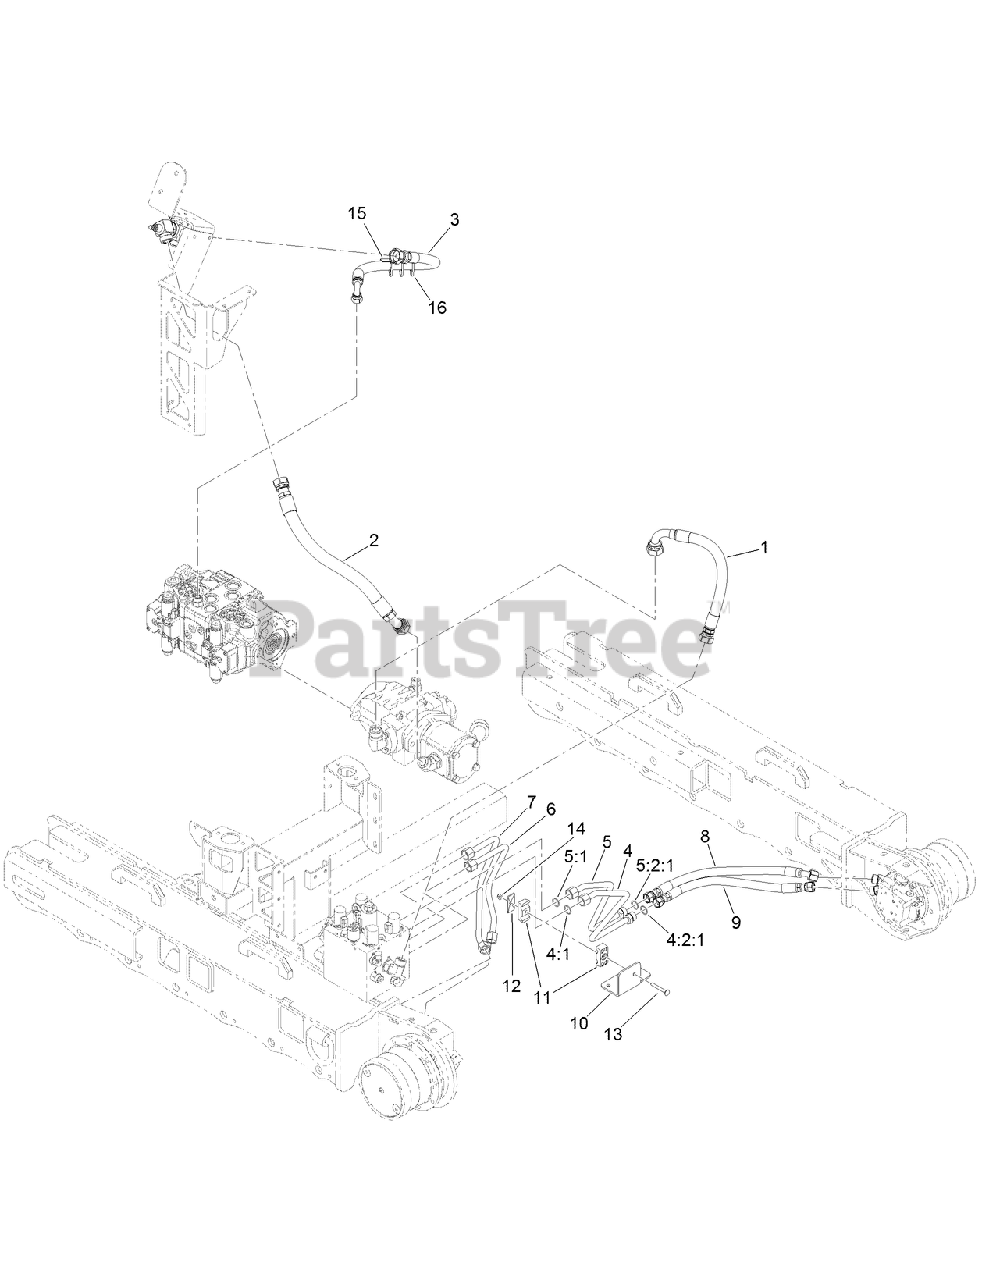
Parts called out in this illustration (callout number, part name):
1	HOSE ASM-HYD
2	HOSE ASM-HYD
3	HOSE ASM-HYD
4	TUBE ASM-HYD
4:1	O-RING
4:2:1	O-RING
5	TUBE ASM-HYD
5:1	O-RING
5:2:1	O-RING
6	TUBE ASM-HYD
7	TUBE ASM-HYD
8	HOSE ASM-HYD
9	HOSE ASM-HYD
10	BRACKET-CLAMP, BATTERY
11	CLAMP-TUBE
12	PLATE-COVER
13	SCREW-CARR
14	NUT-HF, NI
15	PROTECTOR-HOSE
16	TIE-CABLE
